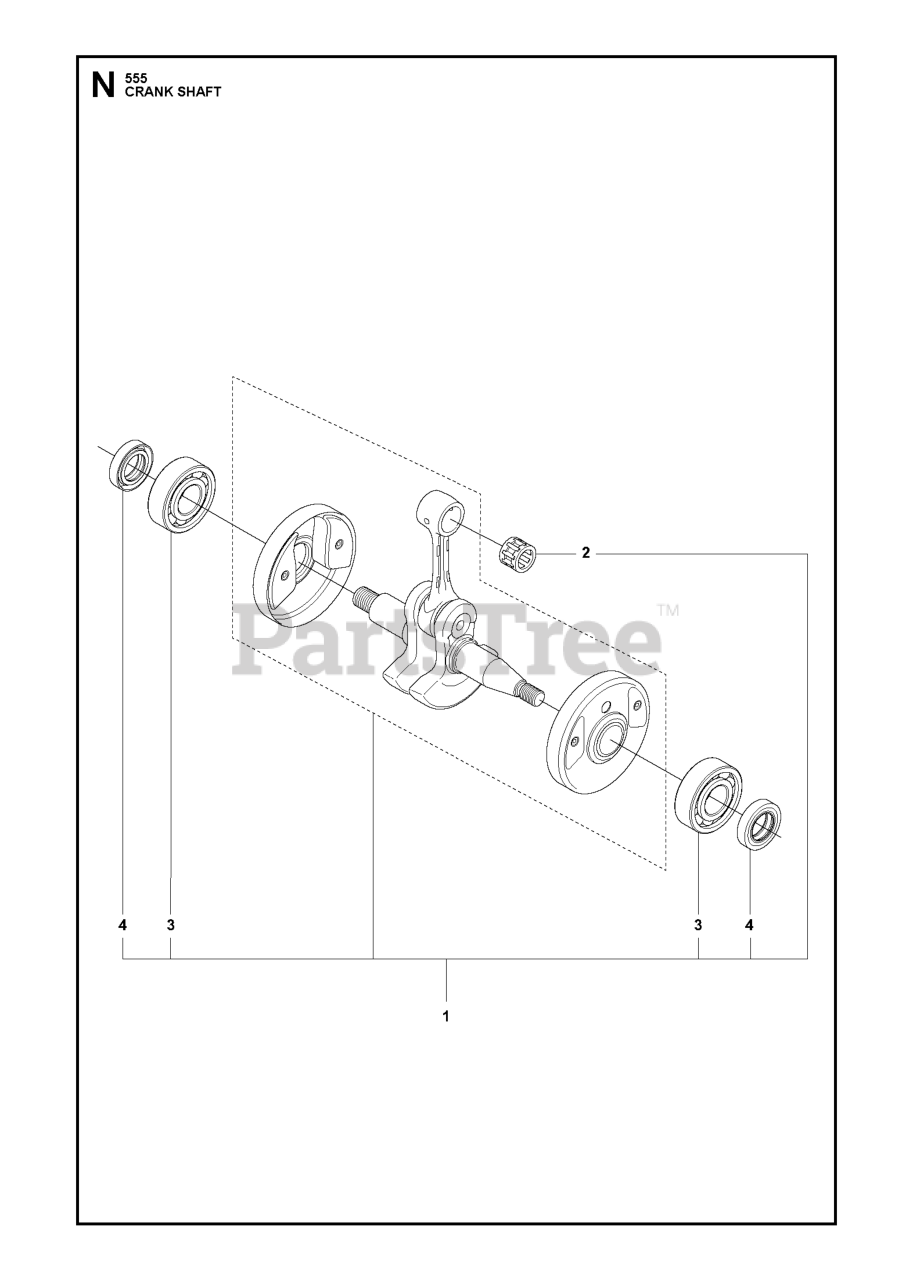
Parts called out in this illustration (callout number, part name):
1	CRANKSHAFT
2	SUPPORT BUSHING
3	BALL BEARING-6202-C3 SKF
4	SEALING RING
